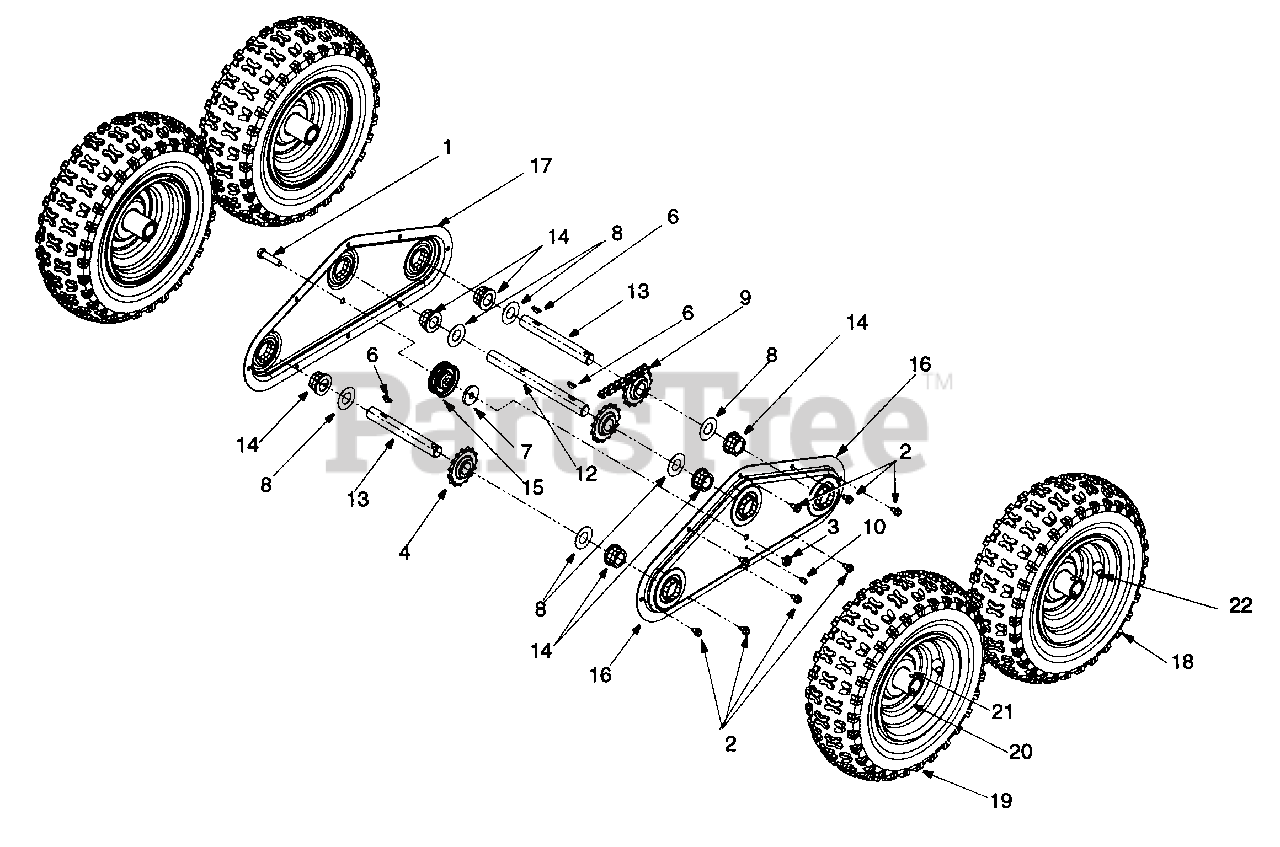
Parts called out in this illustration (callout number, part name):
1	Special Hex Screw: 3/8-24 x 1.5"
2	TT Screw: 1/4-20 x 0.5"
3	Jam Nut
4	Sprocket
5	Chain
7	Flat Washer
8	Flat Washer
9	Lubricant: 6in 1
10	Lube Fitting
11	Grease
12	Drive Axle
13	Wheel Axle
14	Hex Flange Bearing
15	Flat Idler
22	Air Valve
